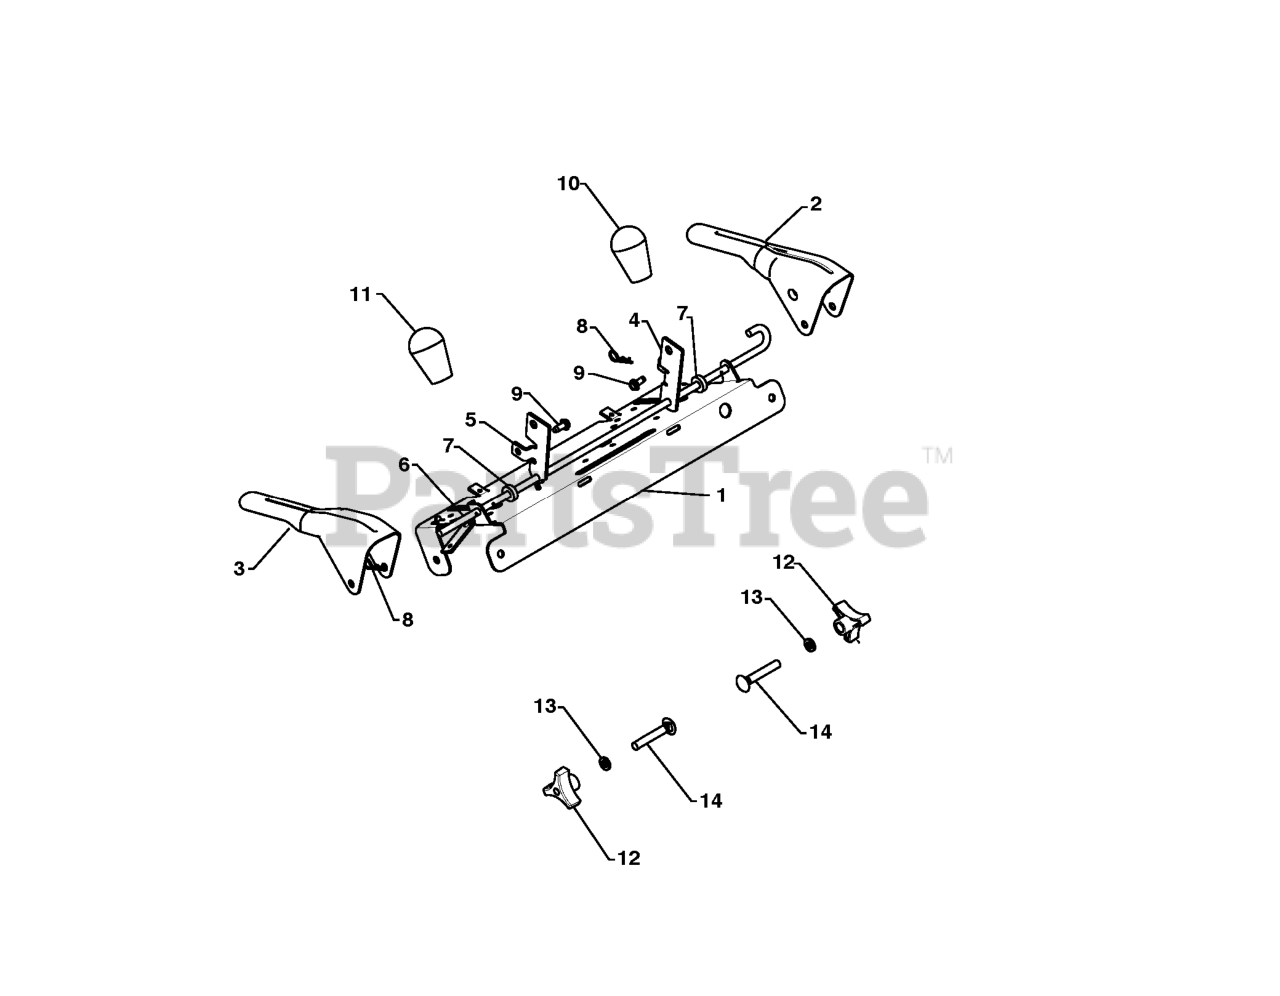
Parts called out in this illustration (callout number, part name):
1	STOP.INTERTLOCK
2	LEVER.CONTROL.LH.BLACK
3	LEVER.CONTROL.RH.GREY
4	ARM.TRACTION.ROD.YZ
5	ARM.IMPELLER.ROD.SNOW
6	BAIL.CONTROL.INTERLOCK
7	SPACER.CONTROL.LEVER
8	SPRING RETAINER
9	SCREW 14-20 X 5/8
10	KNOB LEVER, BLACK
11	RED KNOB SHIFTER
12	KNOB.HANDLE.3/8.TRI-POINT.BLAC
13	WASHER
14	BOLT 3/8-16 X 2-1/4
